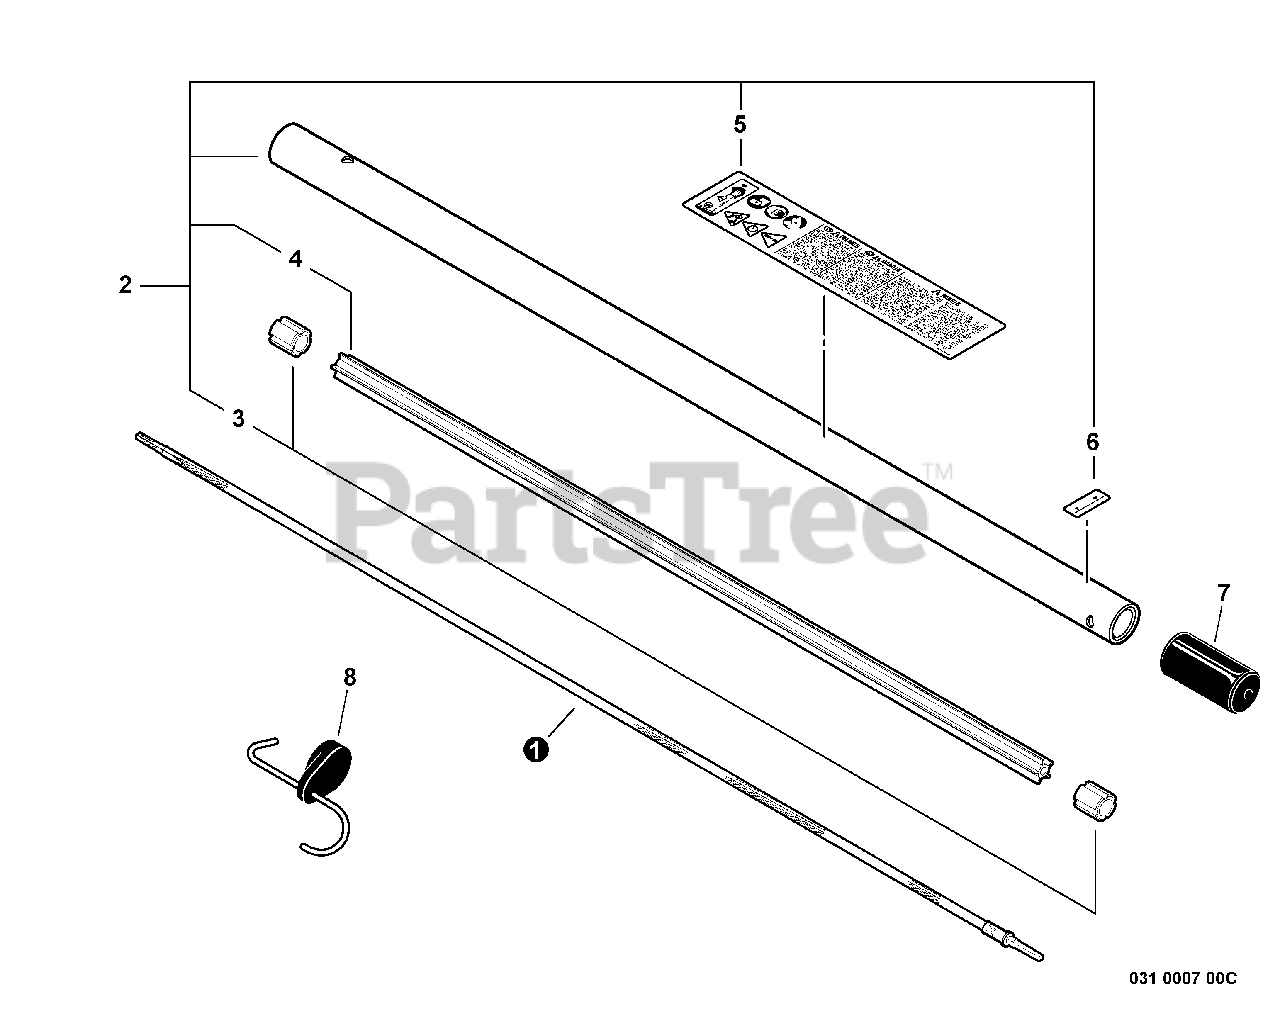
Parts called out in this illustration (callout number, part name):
1	DRIVESHAFT - FLEXIBLE
2	MAIN PIPE ASSY
4	LINER - FLEXIBLE
5	LABEL, CAUTION
6	LABEL - ALIGNMENT
7	CAP, MAIN PIPE
8	HANGER, ATTACHMENT
